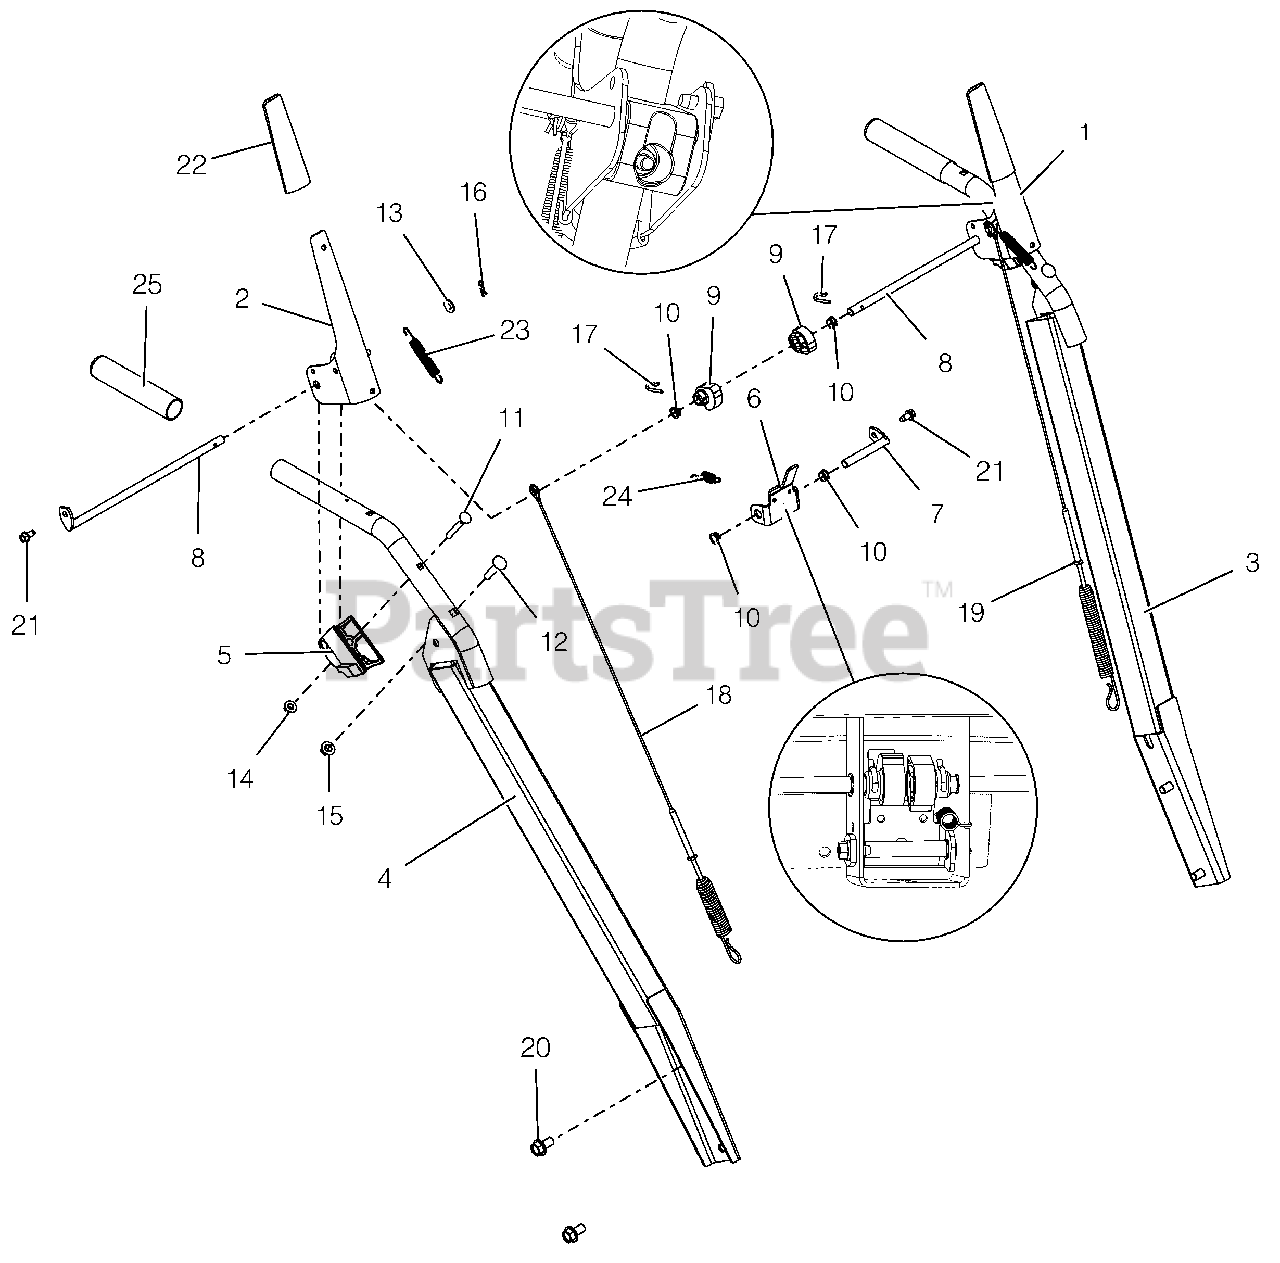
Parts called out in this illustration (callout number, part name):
1	LEVER, CLUTCH-LH
2	LEVER, CLUTCH-RH
3	HANDLEBAR, HEAVYDUTY-PRO LH
4	HANDLEBAR, HEAVYDUTY-PRO-RH
5	BLOCK, CLUTCH PADDLE
6	BRACKET, INTERLOCK ARM
7	ROD, INTERLOCK PIVOT
8	ROD, PADDLE MOUNT - PRO
9	CAM, INTERLOCK
10	BUSHING, POLYLINER-.38 SNAPIN
11	BLT-RDHDXLSQNK .25-20X2.0 G5YZ
12	@BLT-RDHDSQNK .31-18X1.50 G5YZ
13	@WSHR-FL-STL.281X.62X.065 YWZC
14	NUT-LK-CTR-FLG .25-20 YWZC
15	@NUT-LK-TOP-FLG .31-18 YWZC
16	PIN-HAIR INT .06X.18X.77
17	PIN, SPRING CLIP
18	CABLE, AUGER (DELUXE & PRO)
19	CABLE, UPPER TRACTION
20	BLT-SERHFWH .38-16X.75 YWZC
21	SCR-TAP .25-20X.50 HWH TR YWZ
22	SLEEVE, CLUTCH PADDLE-GRAY
23	SPRING, EXTENSION
24	SPRING-EXT .047X.438X1.45
25	GRIP,HANDLE-GRAY
